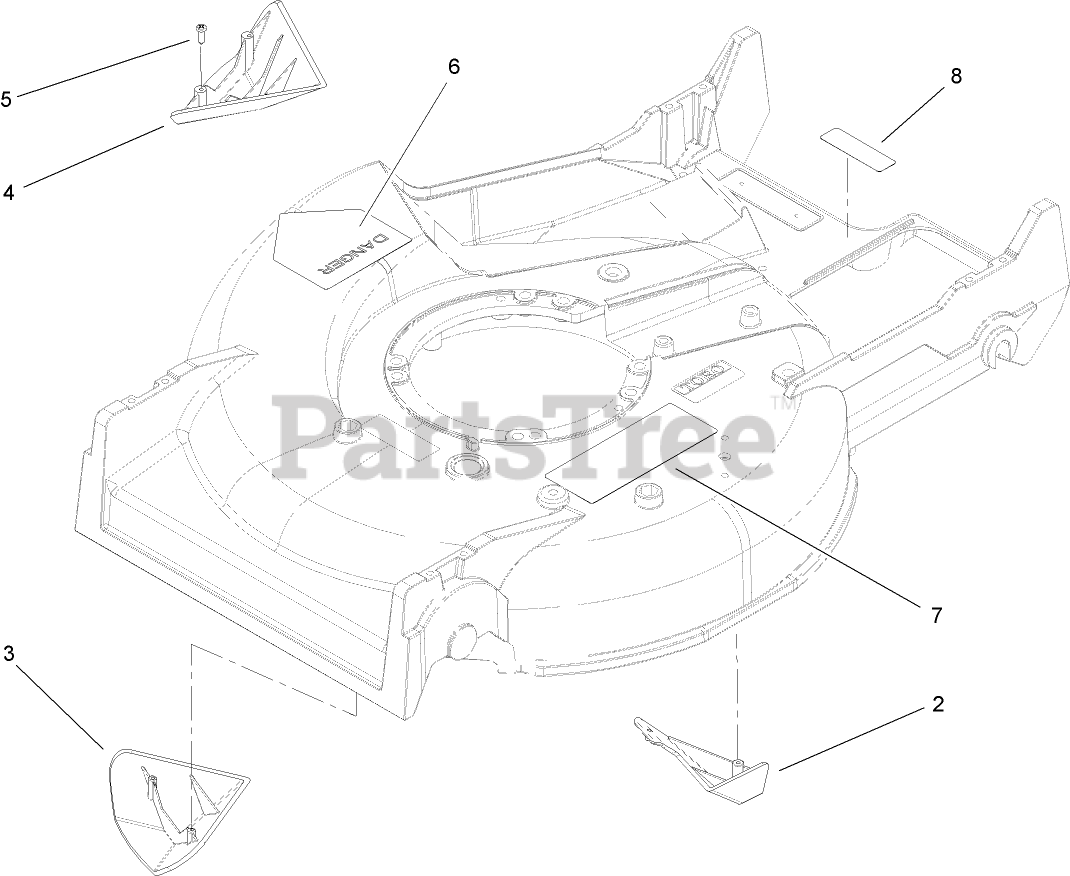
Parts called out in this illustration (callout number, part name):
2	KICKER-REAR
3	KICKER-FRONT
4	KICKER-RH
5	SCREW-PPH
6	DECAL-DANGER
8	DECAL-WARNING
